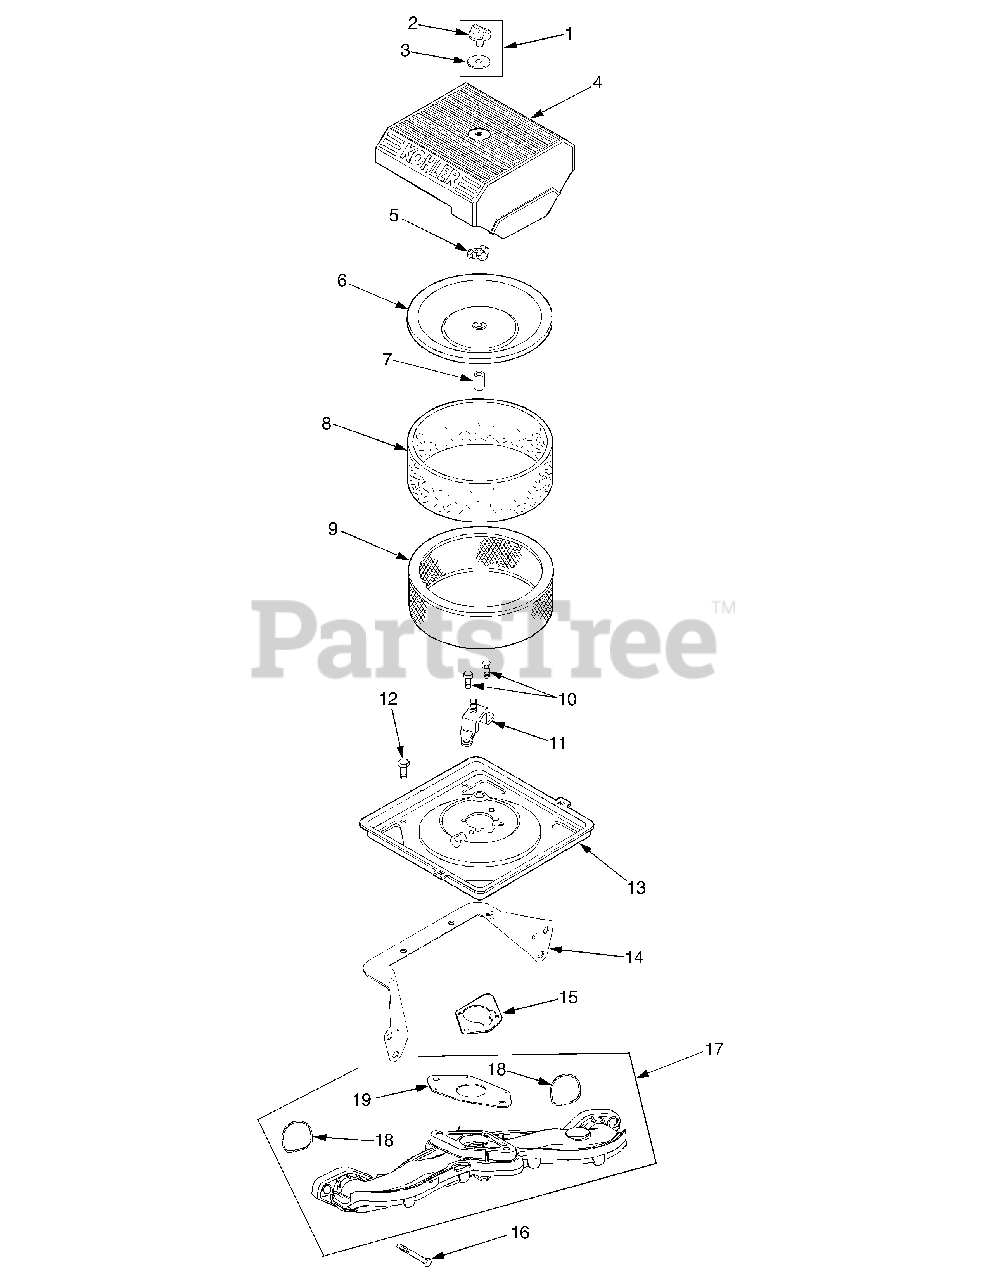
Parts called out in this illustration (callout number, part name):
1	Kit, Knob w/Seal (Incl. Ref #2,3)
3	Seal, Air Cleaner Cover Knob
4	Cover, Air Cleaner
6	Cover, Inner Air Cleaner
7	Seal, Inner Air Cleaner
8	Precleaner, Element, 71mm deep
9	Element, Air Cleaner, 74mm deep
10	Screw, Hex Flange, M6 x 1.0 x16
11	Bracket, Air Cleaner Base
12	Screw, Hex Flng, M5 x 0.8 x 10
13	Base, Air Cleaner
14	Bracket, Air Cleaner Base
15	Gasket, Air Cleaner Base
16	Screw, Hex Flange, M6 x 1.0 x 40
17	Manifold, Intake (Includes Ref. Nos. 15 and 16)
18	O-Ring, Intake Manifold
19	Gasket, Carburetor
